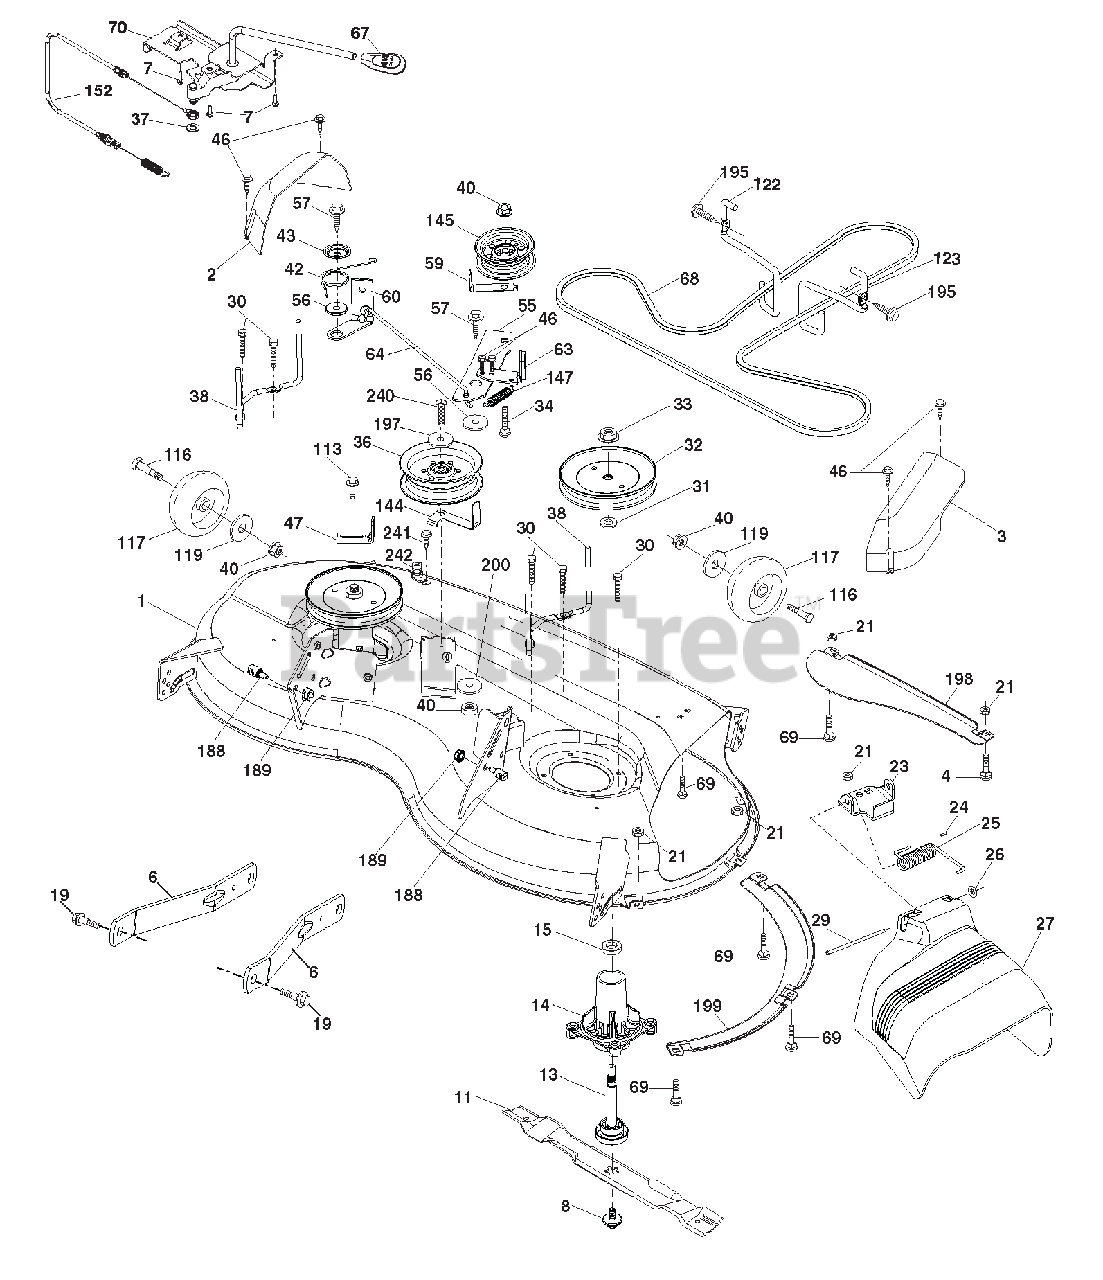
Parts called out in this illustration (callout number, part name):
1	MOWER HOUSING
2	COVER.MANDREL.LH.46"
3	COVER.MANDREL.RH.46"
4	BOLT.HEX.HD.1/4-20UNC X 3/4
6	ARM.SUSPENSION.MOWER.REAR.LD
8	BOLT/WASHER ASM.7/16-20.UNF
11	BLADE.MOWER.46"HI LIFT BAGGER
13	SHAFT ASM.MNDRL.N/GREASEABLE38
14	HOUSING.MANDREL.4PT.SERVICE
15	BEARING.BALL.MANDREL
19	BOLT.SHOULDER
21	Nut, Hex, Crownlock 5/16-18
23	BRACKET.DEFLECTOR.38/42"2005
24	CAP.SLEEVE..80X.112.BLK.MOWER
25	SPRING.TORSION.DFL.38/42/46.GR
26	NUT.PUSH.PHOS.& OIL
27	SHIELD.DEFLECTOR.MOWER 46"BLK
29	ROD.HINGE.42/46"
30	SCREW.THD ROLL.DOD PT.HEX
31	WASHER.SPACER.MANDREL
32	PULLEY.MANDREL.5.438 PD.42"
33	NUT.FLANGE.LOCK.TOP
34	BOLT.CARR.SH.3/8-16X1-1/2.GR5
36	PULLEY.IDLER.4.50.RAW
37	WASHER.13/32 X 13/16 X 16 GA.
38	KEEPER.BELT.MANDREL.PULLEY
40	Nut, Hex, Flangelock 3/8-16
42	SPRING.TORSION.BRAKE
43	SPRING.TORSION.RETAINER
46	SCREW.THD.ROLL.1/4-20 X 5/8
47	BRACKET.CLUTCH.CABLE
55	IDLER.ARM
56	SPACER.RETAINER
57	SCREW.3/8-16X1.SMGML.TAP/R.BLK
59	GUARD.TUV.IDLER
60	ARM.BRAKE.MOWER.38/46"LH.TEX
63	ARM.BRAKE.MOWER
64	LINAGE.ASM.BRAKE
67	HANDLE.CLUTCH.CABLE.LT TEX.428
68	V-BELT.DRIVE.MWR.MECHANICL.46"
69	BOLT.5/16-18HEX.WHS.HD.LCKSERR
70	CLUTCH.ASM.MANUAL
113	BOLT.5/16-18HEX.WHS.HD.LCKSERR
116	BOLD SHLD "A" 2.41 "B" 1.66
117	WHEEL.GAGE.HALF.SPOKED
119	Washer 3/8 x 7/8 x 14 Ga.
122	KEEPER.BELT.ENGINE.LH.LT.TEX
123	KEEPER.BELT.ENGINE.RH.LT.TEX
144	KEEPER.BELT.MOWER
145	PULLEY.IDLER 48"PRIMARY
147	SPRING.RETURN.DECK.38/46"
152	CABLE.CLUTCH.MANUAL
188	STUD.FASTNER.W/'D'ANTI-ROTATIO
189	Nut, Lock Hex Flange 5/16-18 u
195	SCREW.HEXWSH THDR3/8-16X3/4.BL
197	Washer 13/32 x 13/16 x 12 Ga.
198	BAFFLE.CENTER.FRONT
199	BAFFLE.FRONT.RH
200	WASHER.13/32 X 1 X 1/2.11GAHRD
240	BOLT.FIN.HEX.3/8-16X 2-1/4 GR5
242	PORT WASHOUT
